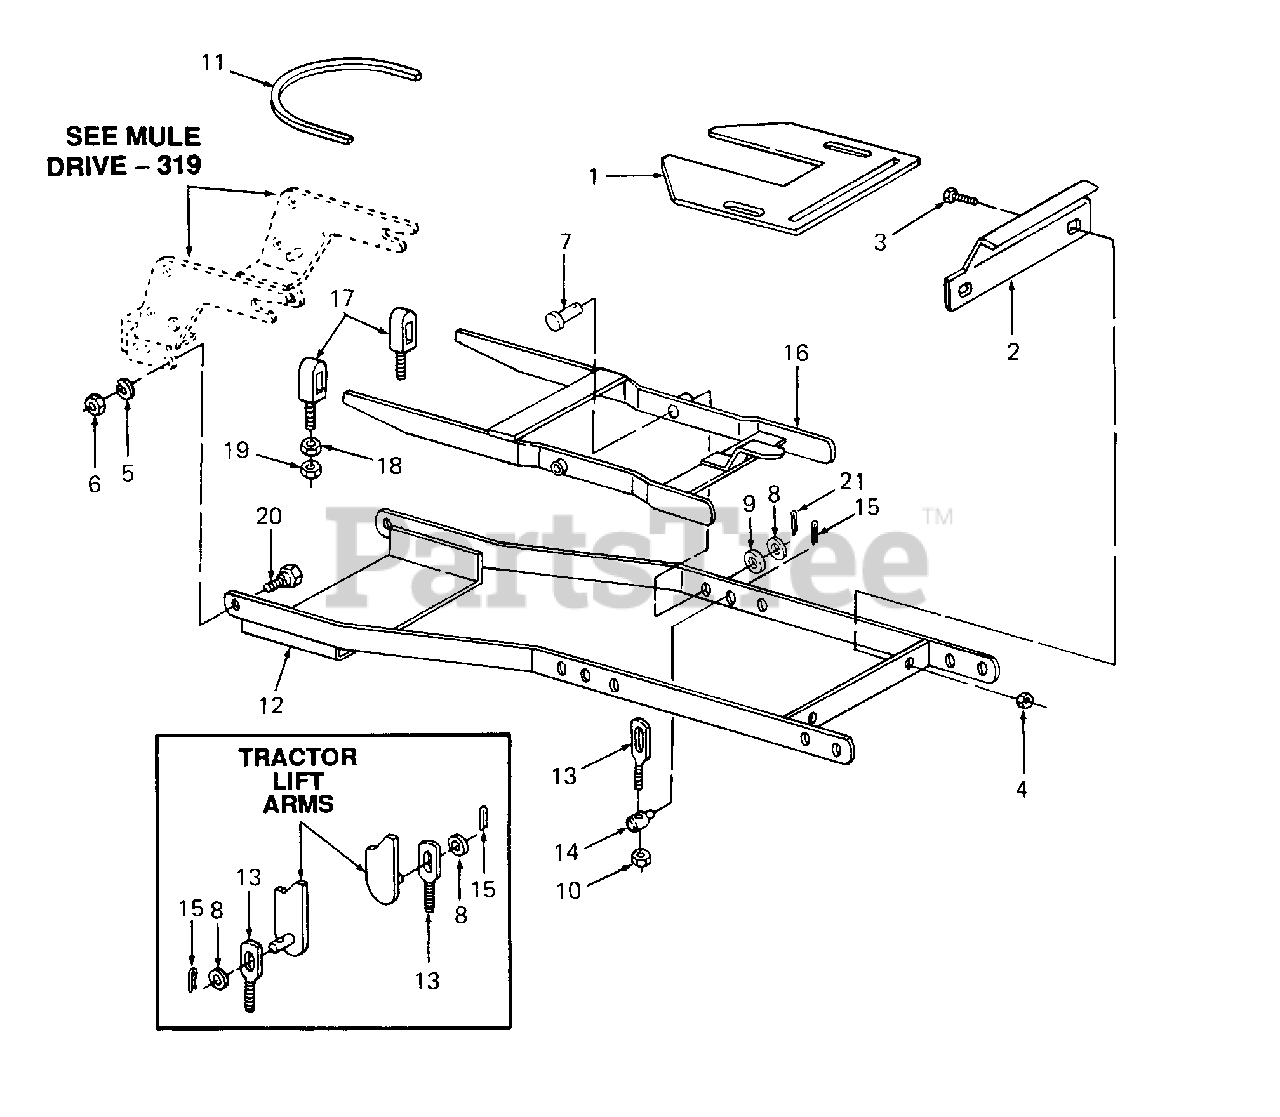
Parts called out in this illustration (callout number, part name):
4	Nut, Hex Lock, 3/8-16
5	Washer, Lock, 3/8
6	Nut, Hex, 3/8-16 GR5
7	Pin, Clevis, .50 Dia X 2.19 Lg
8	Washer, Flat, .51 X 1.0 X .06 Thk
9	Washer, Flat, .51 X 1.0 X .1 2 Thk
10	Nut, Hex Center Lock, 1/2-20
11	Belt, Mule Drive
14	Ferrule, Adjustment
15	Pin, Quick Attach
18	Nut, Hex Jam, 5/8-11 GR5
19	Nut, Hex Insert Top Lock, 5/8-11 GR5
20	Bolt, Shoulder
21	Pin, Cotter, 1/8 Dia X 1.25 Lg
